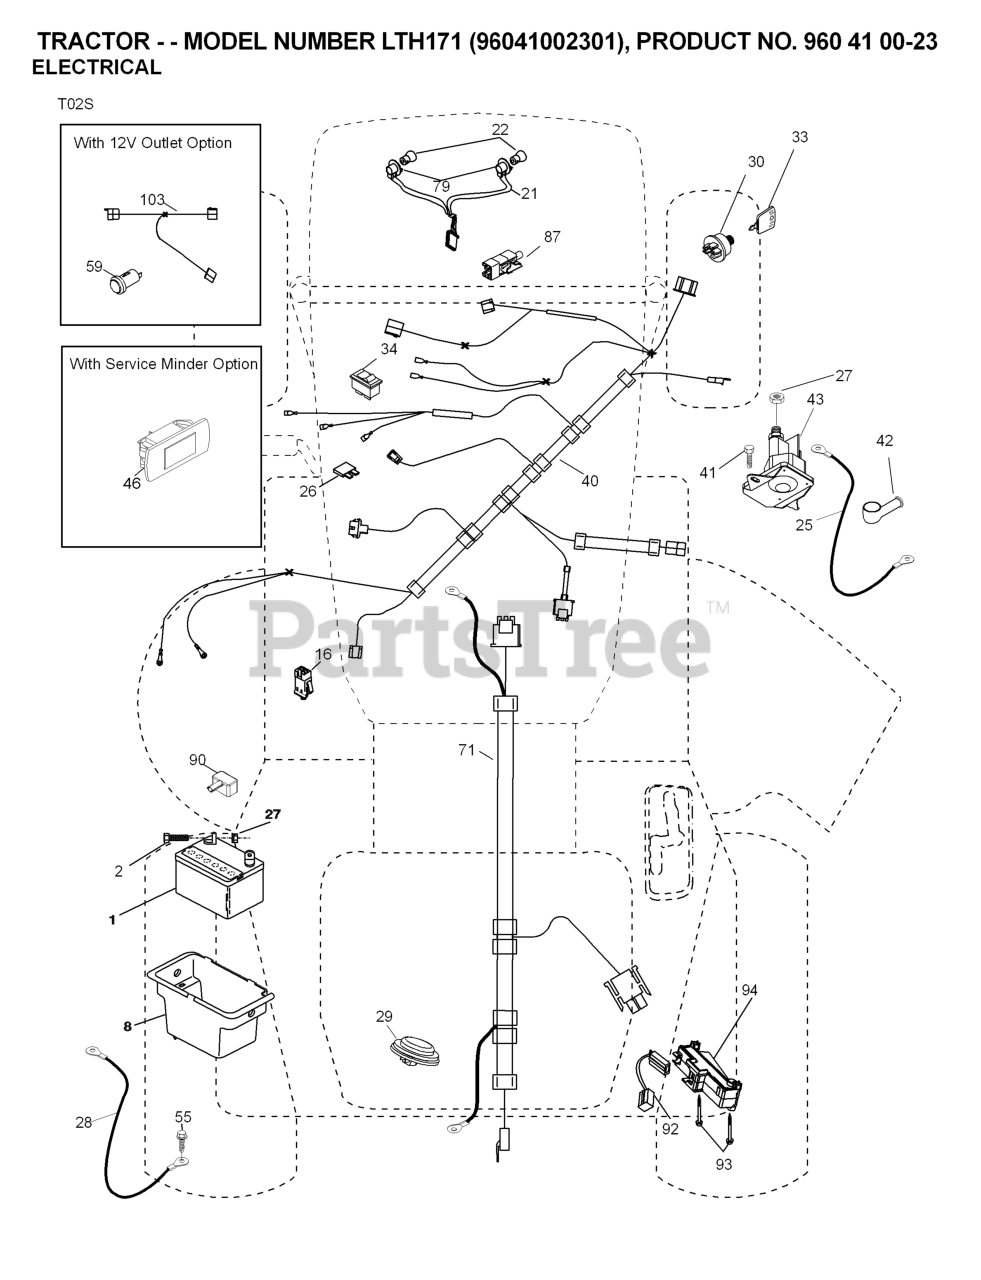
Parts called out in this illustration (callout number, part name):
1	BAIL GROUND DRIVE
2	HCS, M6-1.0 X 70, GR8.8
3	WASHER, 5/16, WAVE
4	GRIP, FOAM (GROUND) 15
6	ROPE GUIDE
7	DECAL, STOP SIGN
8	DECAL, PTO
9	THROTTLE CABLE
10	ZONE CABLE
11	CABLE, GROUND DRIVE
13	SCREW 3/8C X 3/4 HEX CAP
14	NUT.1/4-20.HEX.NYLOC.ZD
15	NUT 3/8-16 NYLOC
